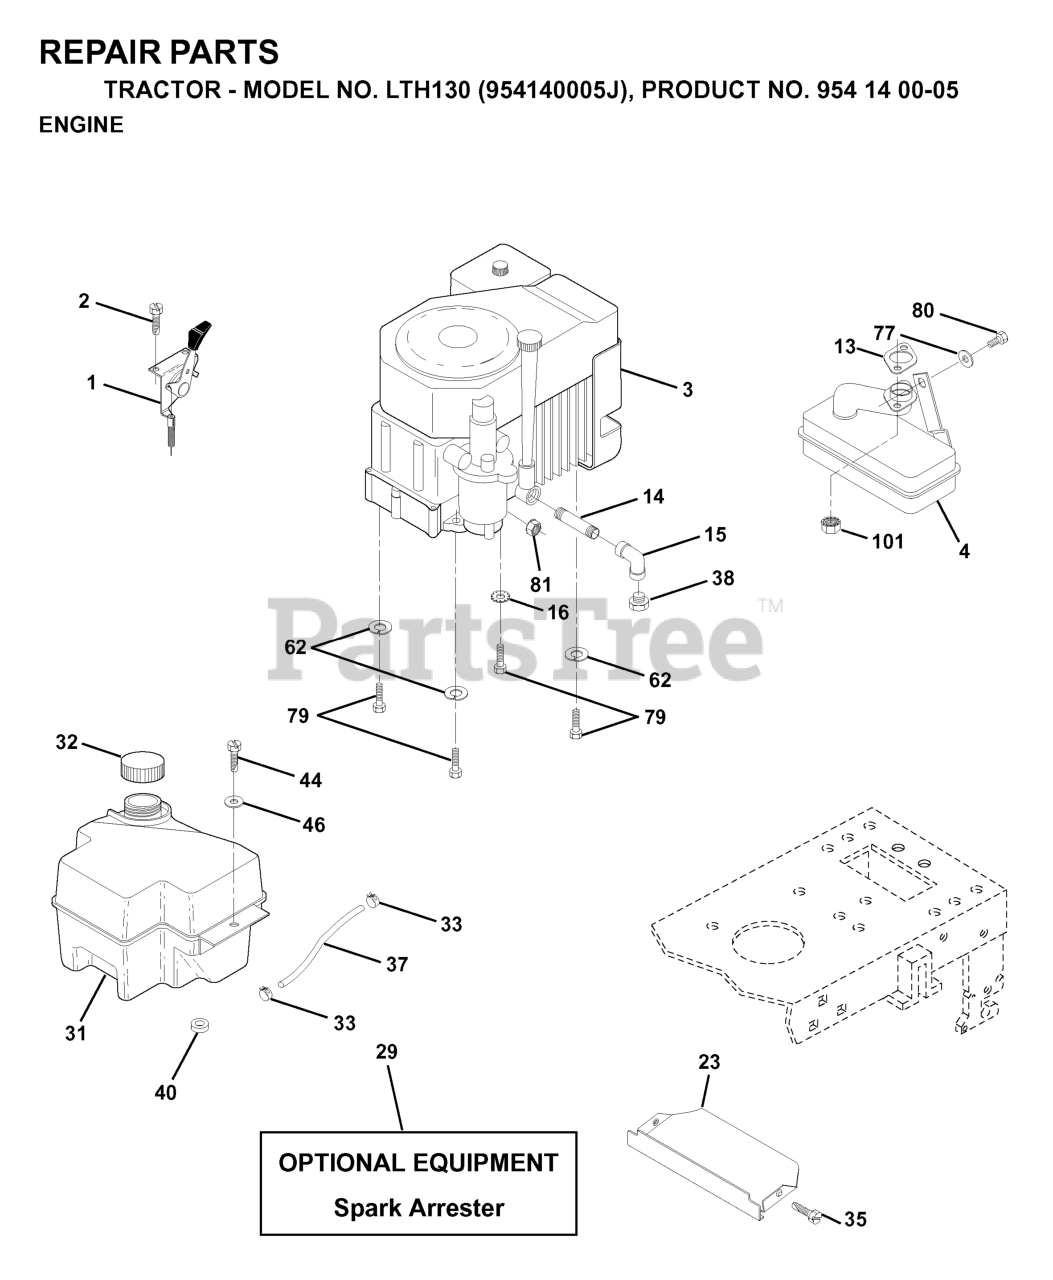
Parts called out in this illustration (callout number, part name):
2	SCREW LT
4	MUFFLER.KOHL.CV.SINGLE.W/PORT
14	Std. Pipe Nipple 3/8 - 18 NPT x 3 1/2
15	ELBOW
16	WASHER EXT TOOTH LOCK 5/16
29	KIT.SPARK ARRESTOR 794945 B&S
31	FUEL TANK
32	FUEL CAP
33	HOSE CLAMP
35	SCREW.THDROL.5/16-18X3/4.TTY
37	LINE.FUEL.20
40	BUSHING.SNAP.NYL.BLK.
44	SCREW HEX CRT
46	WASHER
62	WASHER.LOCK.HVY.HLCL.SPR.5/16
77	WASHER
79	BOLT, HEX
80	Bolt, Hex Head, Fin. 5/16-18 x 1/2
81	NUT FLANGE 1/4-20 STARTER NUT
101	FLANGE NUT
